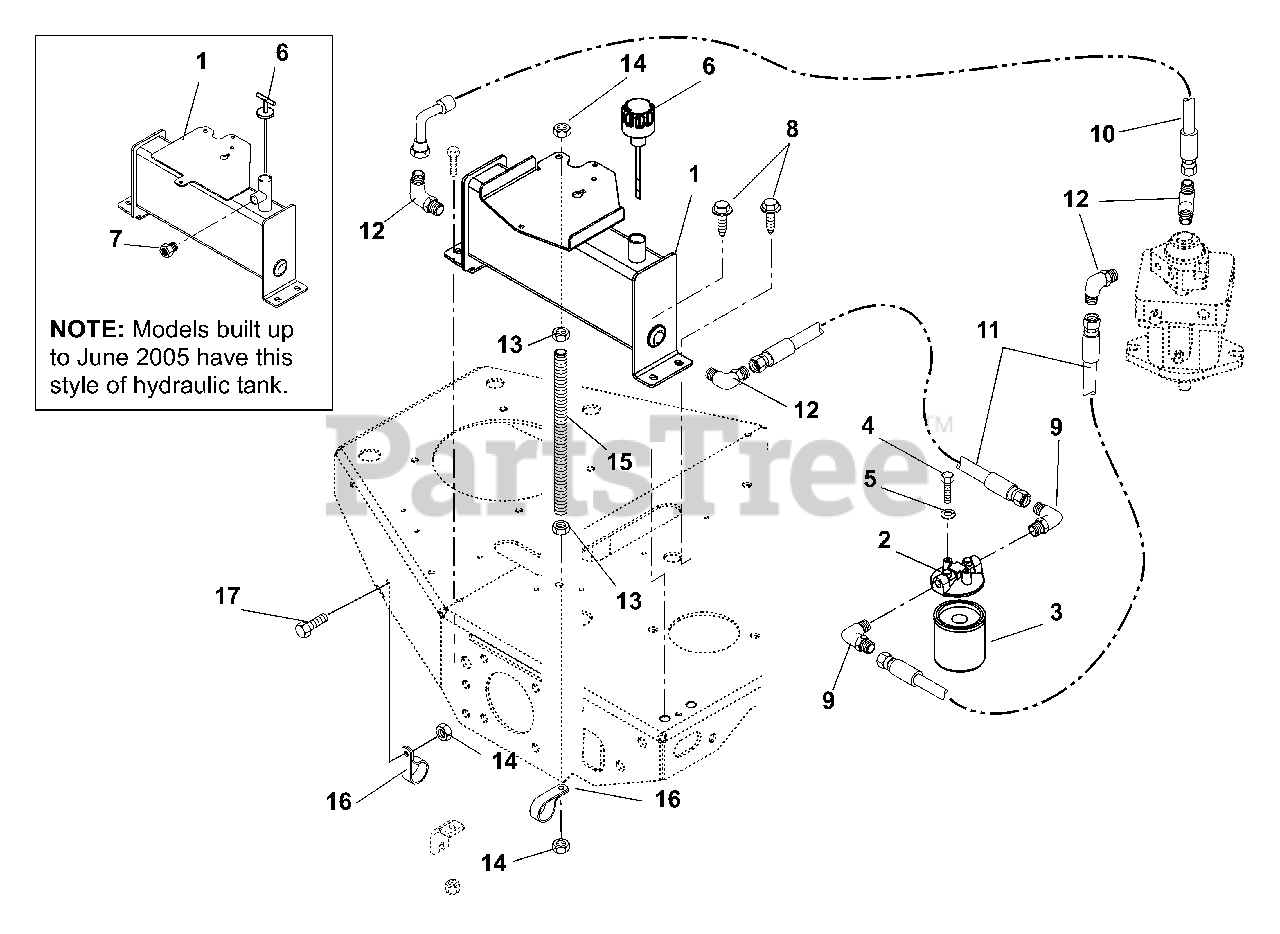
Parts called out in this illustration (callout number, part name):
1	Hydraulic Tank Kit
2	Head, Filter
3	Filter, Oil
4	Bolt-Hex .25-20 x .50 Grade 5
5	Washer-Locking .25 x .062 Regular
6	Dipstick, Hydraulic Tank, Push In
6	Dipstick, Hydraulic Tank, Screw In
7	Plug, Breather .38"
8	Screw-Tapping .38-16 x .75 Hex Washer Head
9	Fitting, Hydraulic
10	Hose, Hydraulic
11	Hose, Hydraulic
12	Fitting, Hydraulic Elbow
13	Nut-Hex .38-16
14	Nut-Locking-Top-Flange .38-16
15	Rod, Extension
17	Bolt-Hex .38-16 x 1.00 Grade 5
